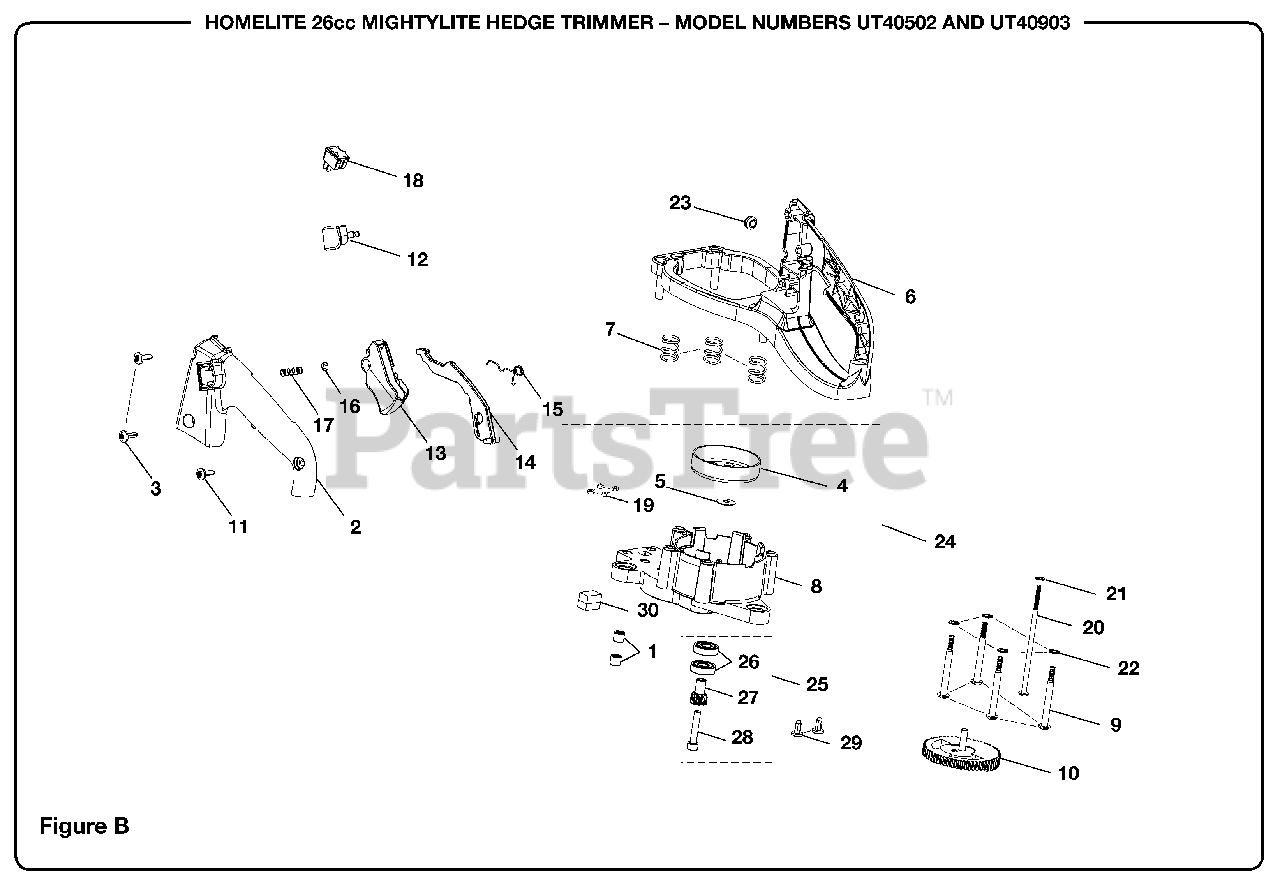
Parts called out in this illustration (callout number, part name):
1	Needle Bearing
2	Left Handle
3	Screw (M5 x 25 mm)
4	Clutch Drum Assembly
5	Bellville Washer
6	Handle (Rear Base)
7	Compression Spring
9	Screw (M5 x 60 mm)
10	Gear & Pin Assembly
11	Screw (M5 x 17 mm)
12	Throttle Lock Pin
14	Throttle Lockout
15	Torsion Spring
16	Retaining Ring
17	Compression Spring
18	Switch
19	Hex Nut (M5)
20	Screw (M5 x 110 mm)
21	Washer (M4.5)
22	Washer (M6)
24	Gearbox Assembly
25	Pinion Assembly
26	Ball Bearing (609ZZ)
28	Screw (M6 x 33 mm)
29	Screw (M5 x 12 mm)
30	Blade Seal
